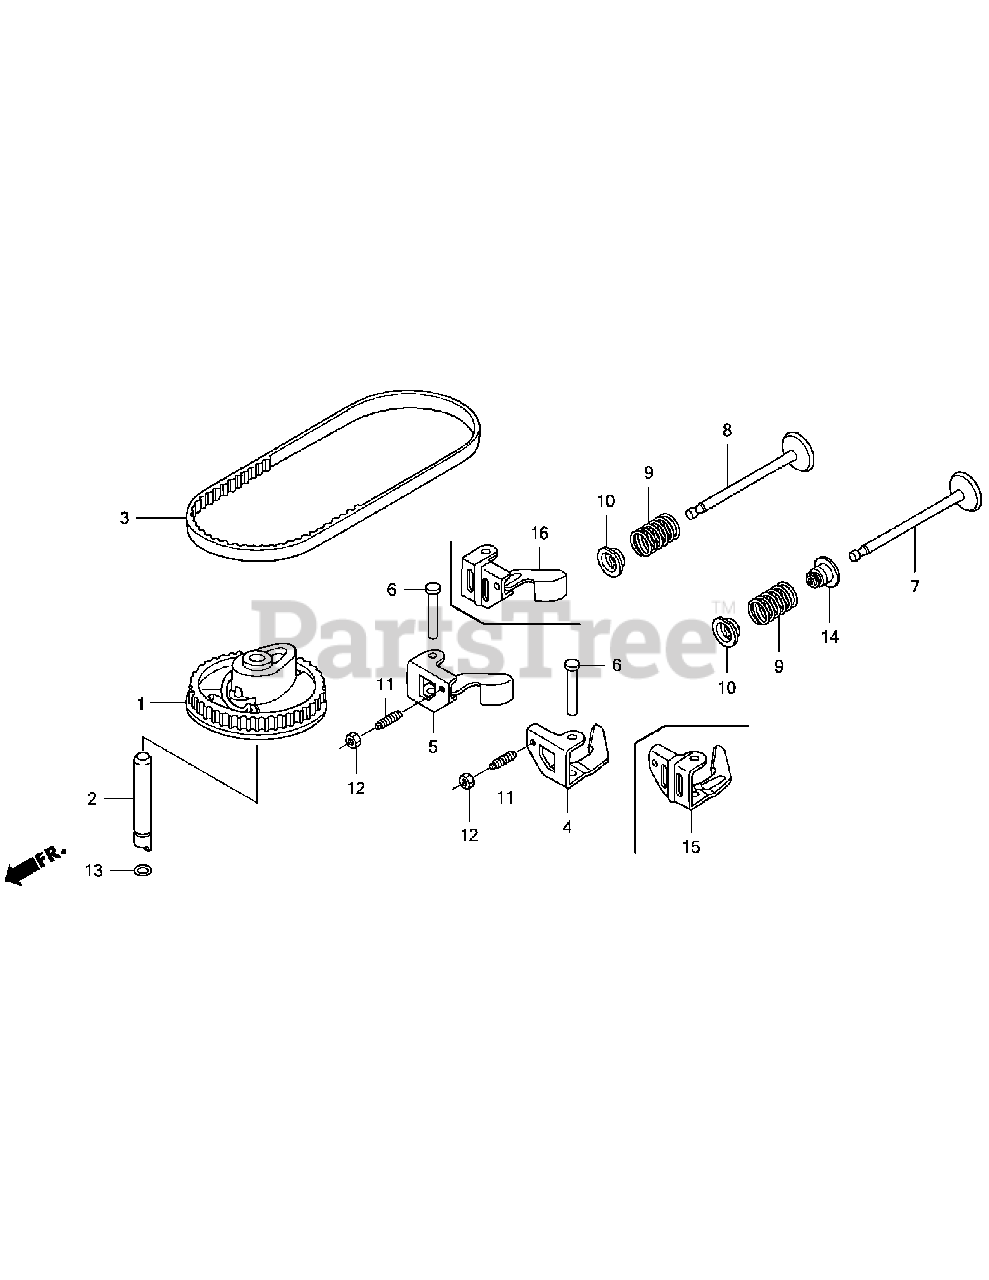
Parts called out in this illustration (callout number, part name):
1	PULLEY, CAMSHAFT
2	SHAFT, CAM PULLEY
3	BELT, TIMING (84HU7 G-200)
6	SHAFT, ROCKER ARM
7	VALVE, IN.
8	VALVE, EX.
9	SPRING, VALVE
10	RETAINER, VALVE SPRING
11	SCREW, TAPPET ADJ.
12	NUT, TAPPET ADJ.
13	O-RING (6.8X1.9)
14	SEAL, VALVE STEM
15	ARM, IN. VALVE ROCKER
16	ARM, EX. VALVE ROCKER
